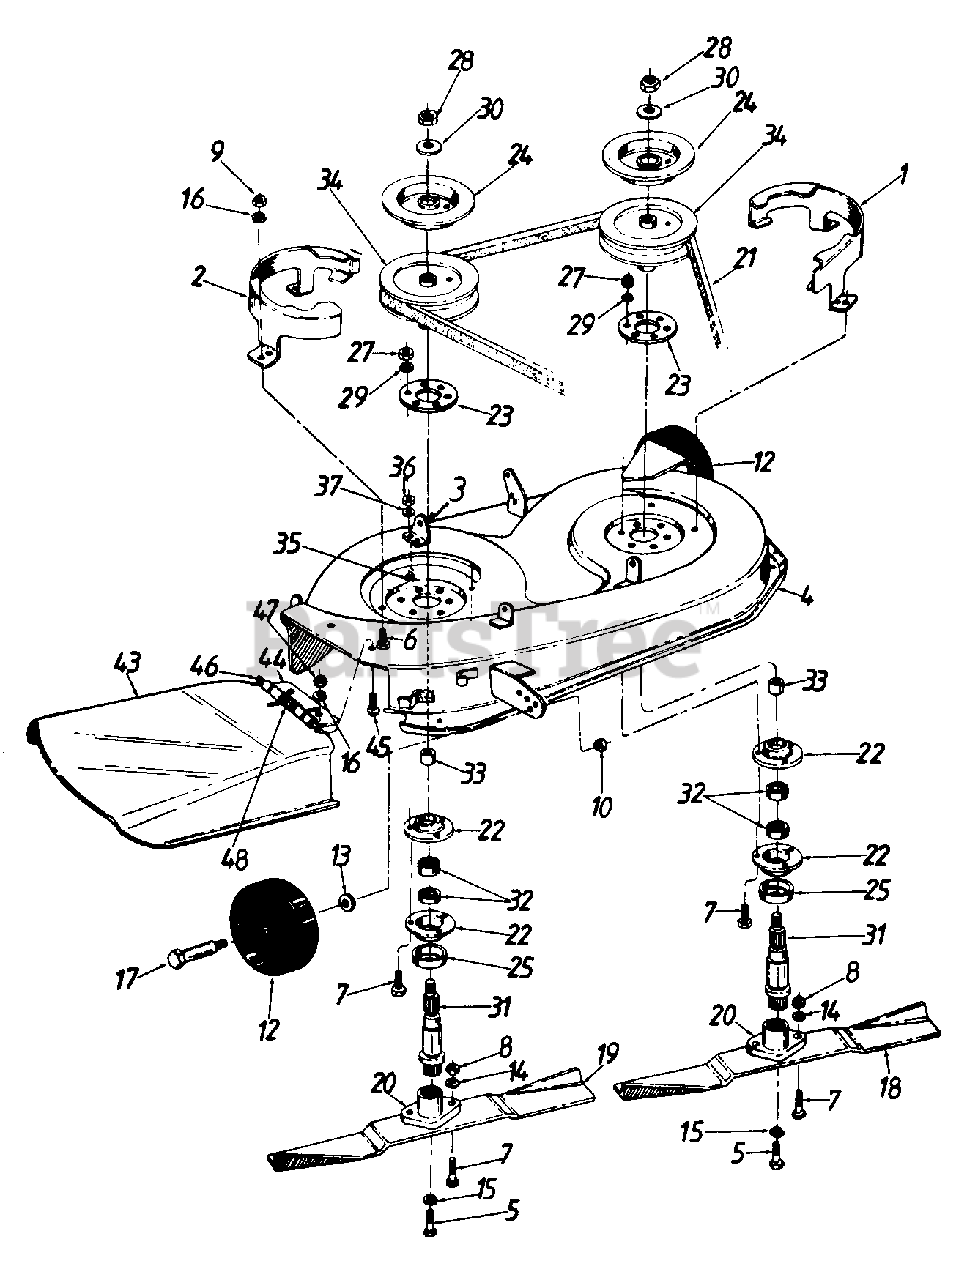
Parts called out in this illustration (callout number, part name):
5	Hex Bolt 3/8-24 x 1.0" Lg.
6	Hex Bolt 1/4-28 x .62" Lg.
7	Hex Bolt 5/16-24 x 1.0" Lg.
8	Hex Nut 5/16-24 Thd.
9	Hex Nut 1/4-28 Thd.
10	Hex L-Nut 3/8-16 Thd.
12	Deck Wheel
13	Bell-Wash. .380" I.D. x .88
14	L-Wash. 5/16" I.D.
15	L-Wash. 3/8" I.D. H.D.
16	Bell-Wash. .265" I.D. x .75
17	Shld. Bolt .498" Dia. x 1.53 Lg.
18	L.H High-Lift Blade
19	R.H. High-Lift Blade
20	Blade Adapter
21	V-Belt
22	Bearing Housing
23	Reinforcement Plate
24	Brake Disc
25	Bearing Shield
27	Hex Nut 5/16-24 Thd.
28	Hex Jam Nut 5/8-18 Thd.
29	L-Wash. 5/16" I.D.
30	L-Wash. 5/8" I.D.
31	Blade Spindle
32	Ball Bearing
33	Spacer
34	5n Dia. Pulley
35	Hex Scr. 1/4-20 x .62" Lg.
36	Hex Nut 1/4-20 Thd.
37	L-Wash. 1/4" I.D.
43	Chute Ass'y.
44	Chute Bracket
45	Truss-Mach. Scr. 1/4-20 x .75" Lg.
46	Hinge Pin
47	Hex Jam Nut 1/4-20 Thd.
48	Torsion Spring 1.14" Lg.
